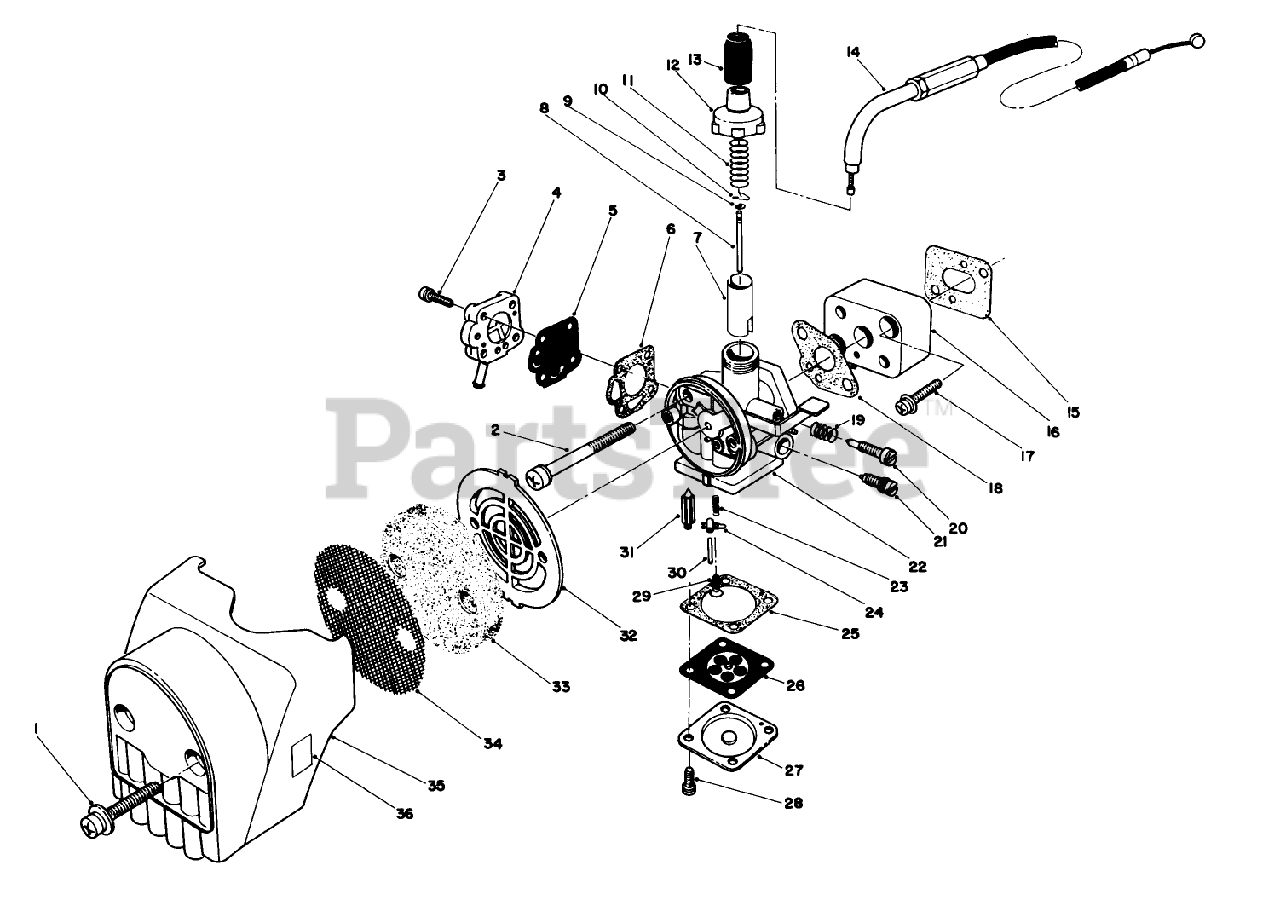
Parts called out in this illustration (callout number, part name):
2	SCREW W/ WASHER
13	AIR SEAL
15	GASKET, INSULATOR
21	MAIN NEEDLE
22	CARBURETOR (D)
24	FLOAT ARM
25	DIAPHRAGM GASKET
27	DIAPHRAGM COVER
29	FLOAT SCREW
33	ELEMENT
35	COVER, CLEANER
36	CHOKE LABEL
